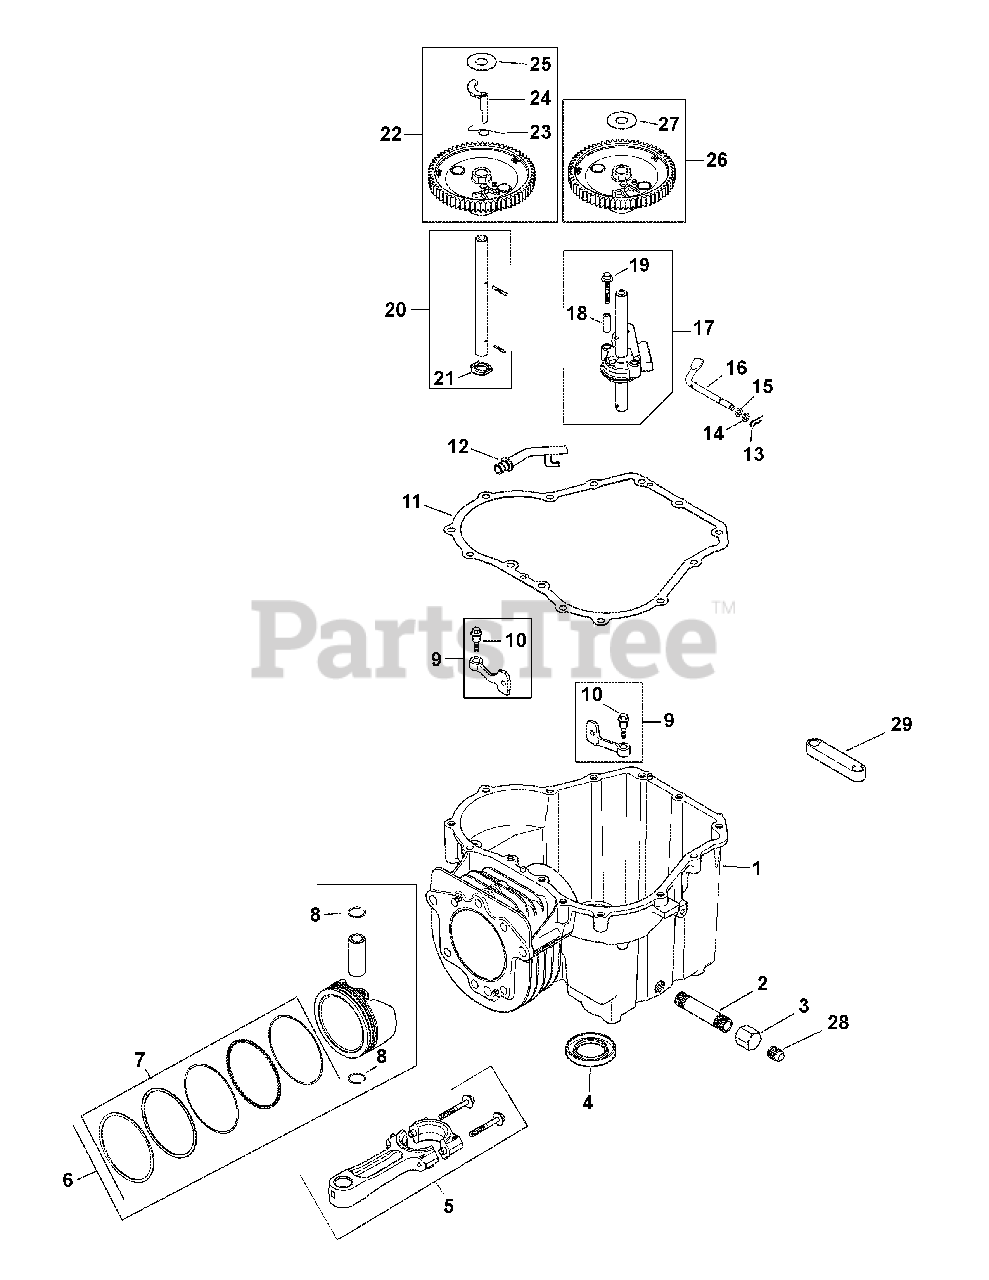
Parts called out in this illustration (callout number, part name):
1	Crankcase
2	Fuse Block
3	Fuse Block
4	Oil Seal
5	Connecting Assembly Rod
6	Piston W/ Ring Set Kit, 94mm
7	Ring Set (94mm)
8	Piston Pin Retainer
9	Cam Lever Ass. Kit
10	Shd. Thd. Frm. Screw, M6 X 1 X 26
11	Fuse Block
12	Drainback Tube
13	Hitch Pin Clip
14	Flat Washer, 6 Mm
15	Flat Washer, 1.4
16	Governor Cross Shaft
17	Oil Pump Assembly Kit
18	Oil Pump Screw Spacer
19	Oil Pump Screw
20	Cam Center Shaft Kit
21	Thrust Washer
22	Camshaft Assembly Kit
24	Acr. Weight
25	Thrust -Acr. Washer
26	Camshaft Assembly Kit
27	Thrust -Acr. Washer
28	Square Head Pipe Plug, 3.8
29	Fuse Block
30	Fuse Block
31	Fuse Block
32	Fuse Block
33	Fuse Block
